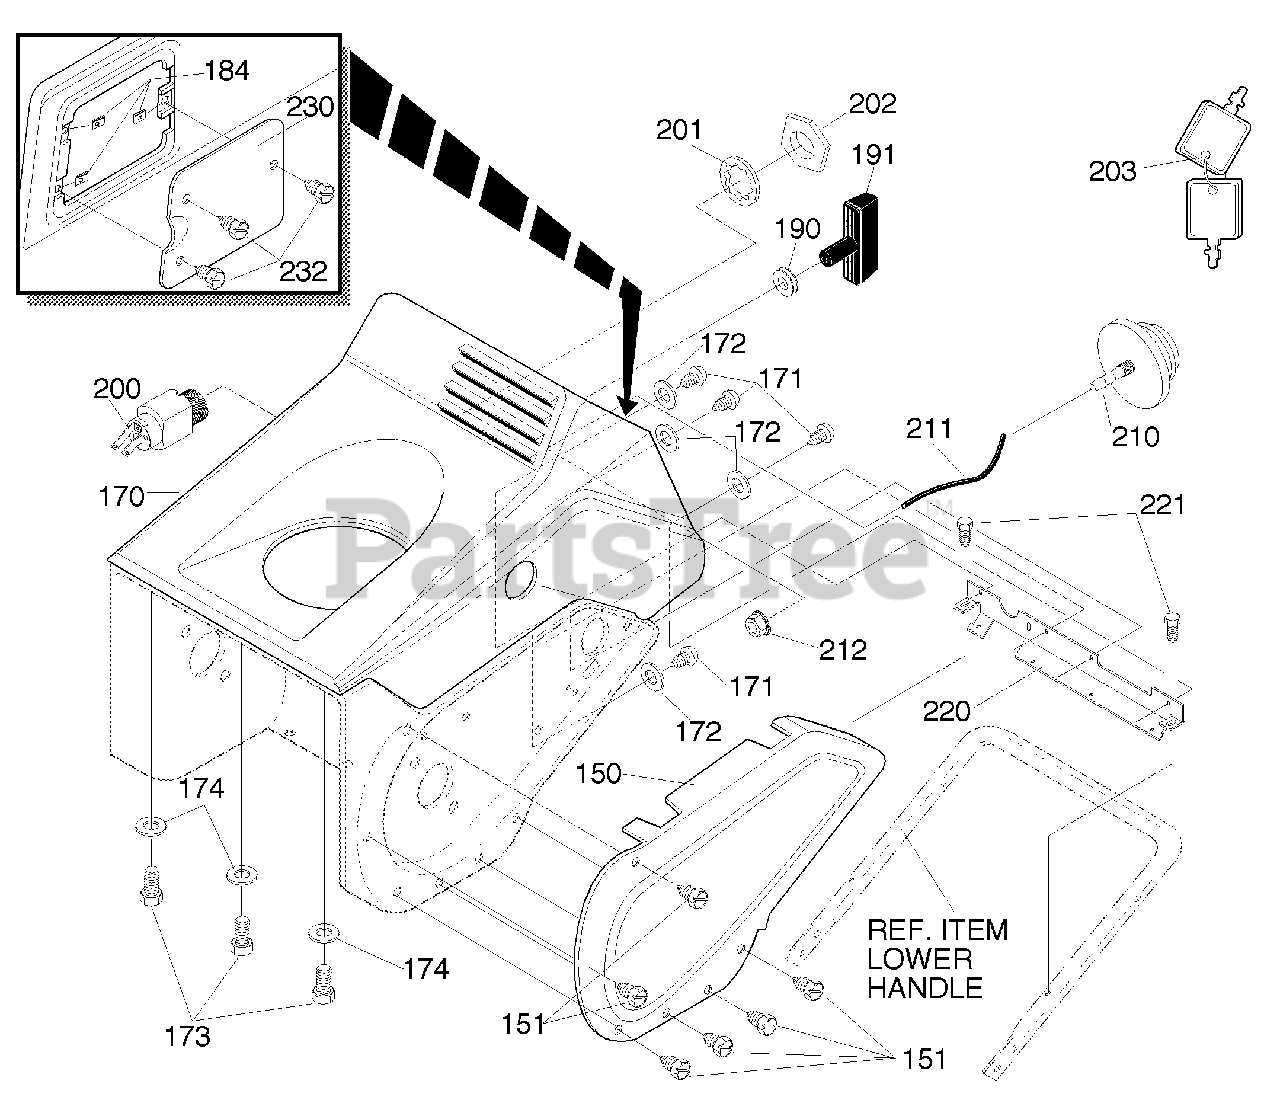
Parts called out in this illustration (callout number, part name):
150	COVER, BELT
151	SCREW,10-24 X .38
170	COVER, TOP
171	SCREW, #10-24 X .63
172	WASHER, FLAT
173	SCREW, #10-14 X .63
174	WASHER, FLAT
184	NUT, TINN "U"
190	GROMMET & WASHER, ROPE GUIDE
191	KNOB, PLASTIC
200	SWITCH, IGNITION
201	WASHER, REGINTLK
202	NUT, 5/8-32 HXHD IGN SWIT
203	2 KEYS & RING, ASSY
210	PRIMER, ENGINE 2CY
211	HOSE, PRIM 5.75 LG
212	NUT, 1/4-20 HEXKEPS
220	BRACKET, SHROUD MNTG
221	SCREW, #10-24 X .63 TRPHTAP
230	DOOR, ACCESS
232	SCREW #10-16 X .75
